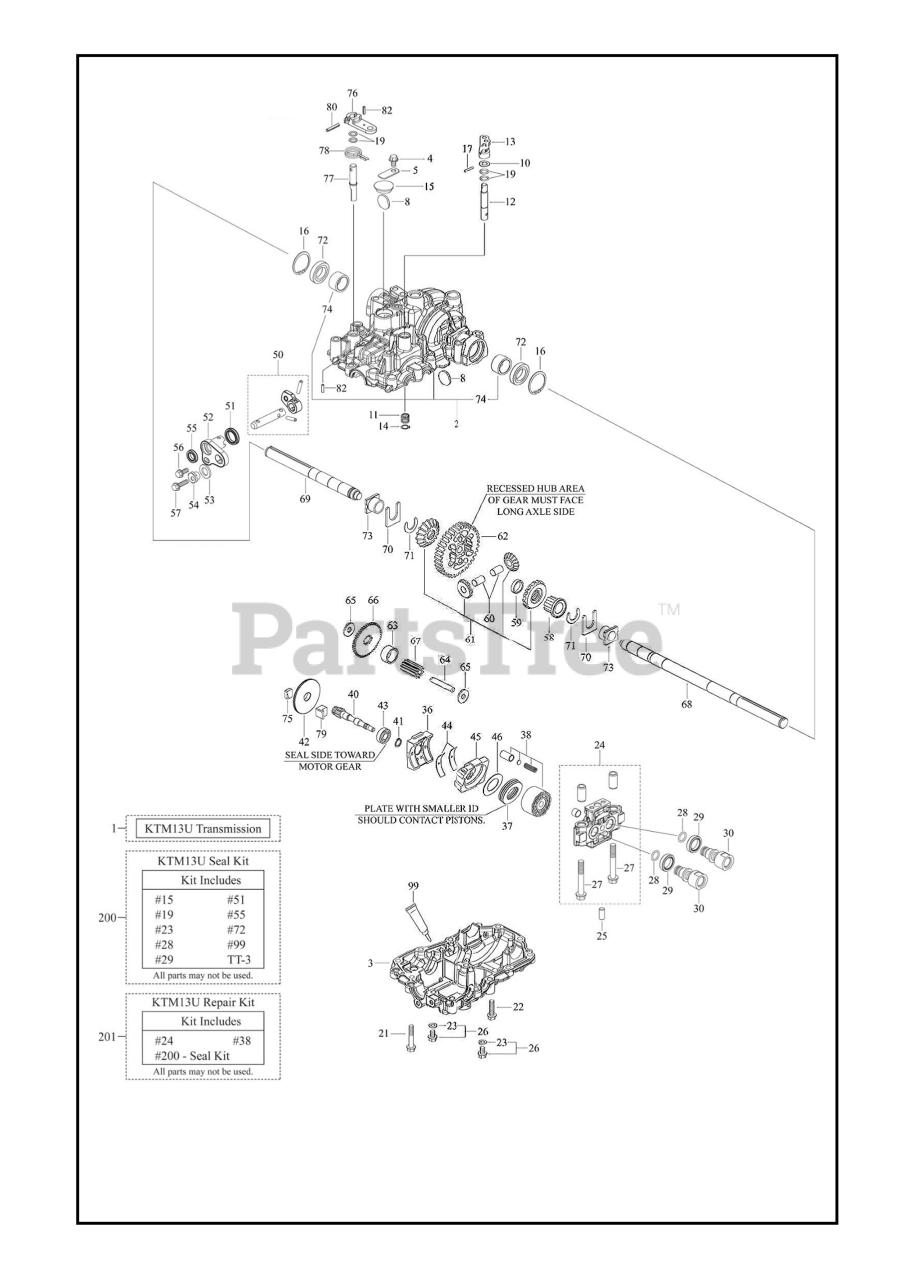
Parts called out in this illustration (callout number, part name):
41	SNAP RING S15
44	METAL THRUST
55	SEALING
78	RETURN SPRING
